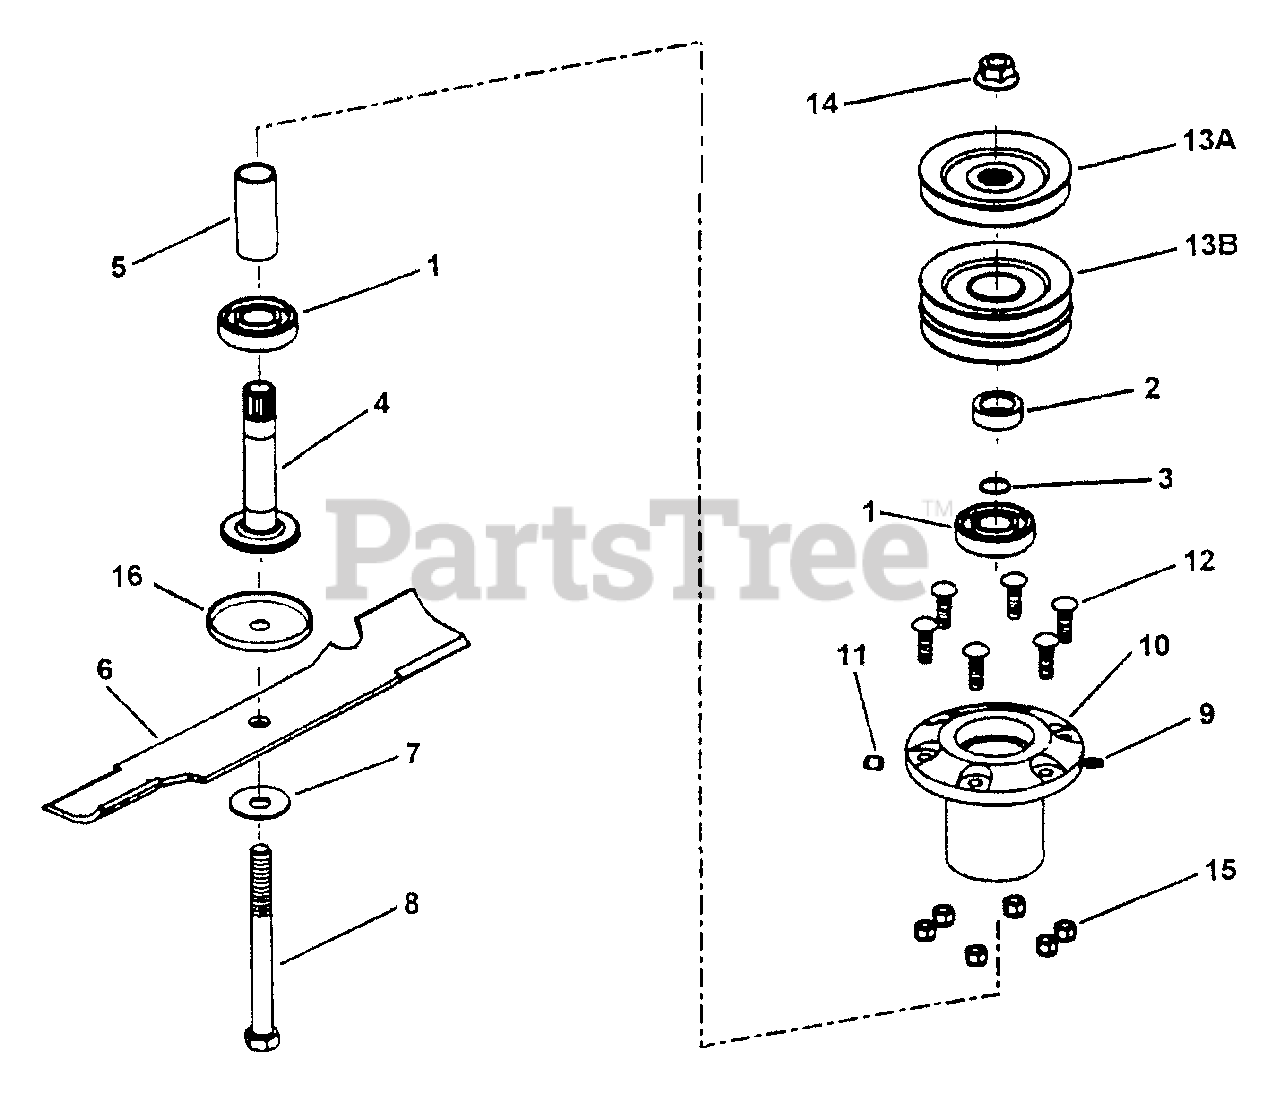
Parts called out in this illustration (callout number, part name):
1	BEARING, Sealed
2	WASHER, Spindle
3	SNAP-RING, Spindle Shaft
4	SHAFT, Spindle
5	SPACER, Bearing
6	BLADE, 16-1/2" (48" Deck)
7	WASHER, Beveled
8	BOLT, 5/8-18 x 6-5/8" Hex Head, Grade 5
9	LUBE FITTING, 1/4-28 Thread Forming
10	HOUSING, Cutter
11	VENT, Spindle
12	BOLT, 3/8-16 x 1-1/4" Rib Necked
13A	PULLEY, Spindle (48" Deck LH & RH)
13B	PULLEY, Spindle (48" Deck/Drive)
14	NUT, 5/8-18 Hex Flange Lock, Grade 5
15	NUT, 3/8-16 Hex Nyloc
16	CUP, Spindle Cover
